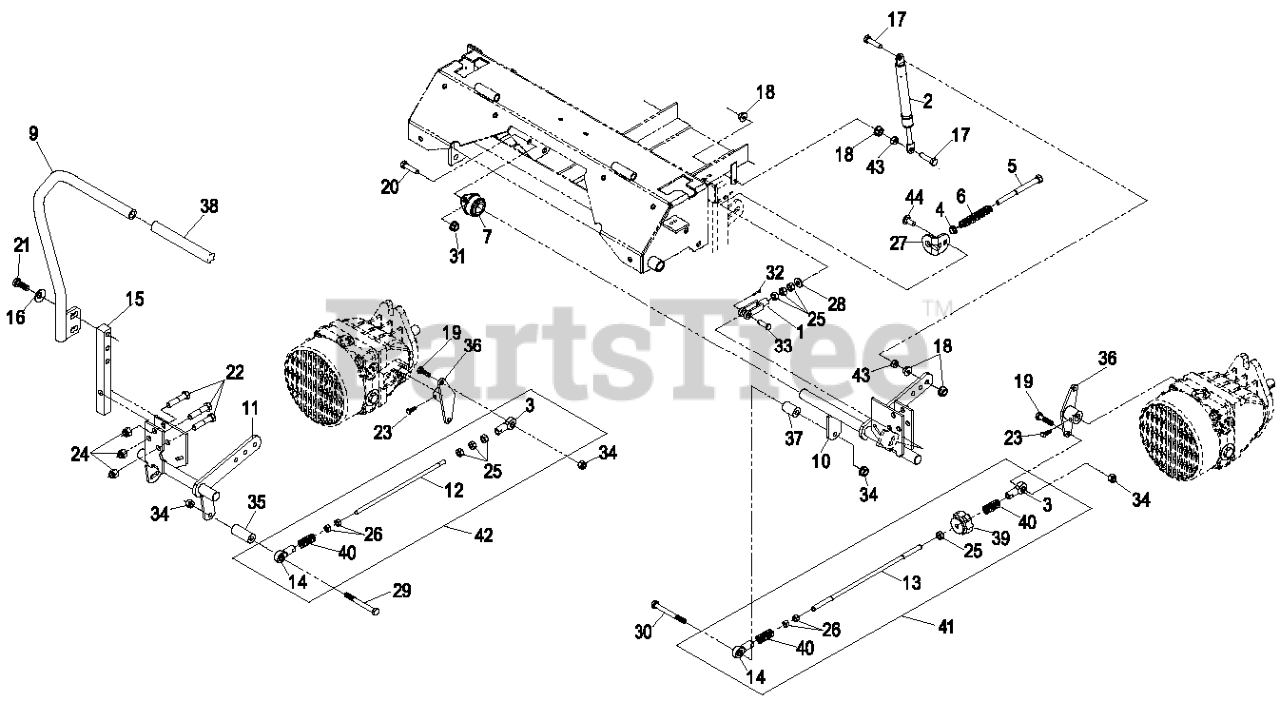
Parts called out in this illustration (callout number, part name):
1	YOKE-ADJUSTABLE
2	DAMPER-CONTROL, MOTION
3	BALLJOINT-RH
4	BUSHING-NYLON, FLANGED
5	BOLT-RETURN, NEUTRAL
6	SPRING-RETURN, NEUTRAL
7	BEARING-FLANGE, SIDE
9	ASM.RH LEVER/GRIP
11	CONTROL-MOTION, RH
12	LINK,XP HYDRO CONNECT RH
13	LINK,TRACKING ROD XP
14	BALLJOINT-LH
15	ARM-SHAFT, CONTROL
16	WASHER-BELLEVILLE
17	SCREW-HH
19	SCREW-HH
20	SCREW-HH
21	SCREW-HH
22	SCREW-HH
23	SCREW-SET
24	NUT-LOCK, NI
25	NUT-HEX
27	TAB-ADJUSTMENT
28	WASHER-FLAT
29	SCREW-HH
30	SCREW-HH
31	NUT-HHF, WHIZ
32	PIN-COTTER
33	PIN-CLEVIS
34	NUT-LOCK, NI
35	SPACER-CONTROL, HYD
36	ARM-CONTROL, HYDRO
37	SPACER-HYDRO CONTROL, LH
38	GRIP,CONTROL LEVER
39	KNOB-TRACKING
40	SPRING-COMPRESSION
41	TRACKING ROD ASM
42	RH HYD CONNECT LINK ASM
43	NUT-HEX
44	SCREW-CARR
